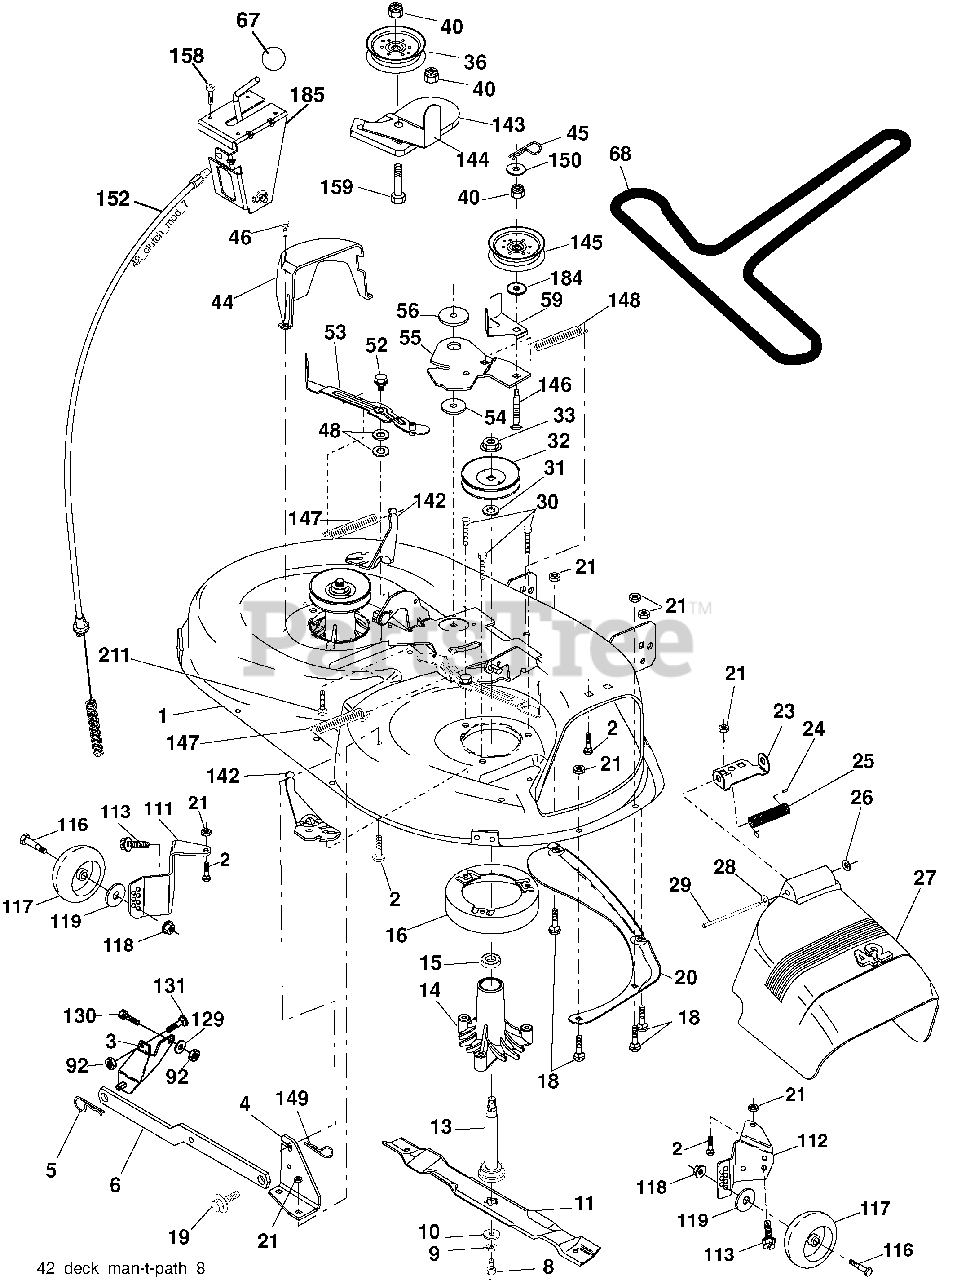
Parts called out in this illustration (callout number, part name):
1	Mower Deck Assembly, 42"
2	Bolt
3	Bracket Asm Fr. Sway Bar 3/42
4	Bracket Asm Deck 42" Sway Bar
5	Retainer Spring
6	Bar Sway Deck
8	Bolt 7/16-20
9	Washer, Lock
10	Washer, Hardened (The following Blades are available)
11	Blade Mower 42” Hi-Lift (for bagging and discharging)
11	Blade, Mulching 42” Std (for mulching mowers only)
11	Blade Mulching 42” Premium (For better wear when mulching)
13	Shaft As sem bly, Mandrel, Vented
14	Housing, Mandrel
15	Bearing, Ball, Mandrel
16	Stripper, Mandrel Deck
18	Bolt, Carriage 5/16-18 x 5/8
19	Bolt, Shoulder
20	Baffle, Vortex
21	Nut
23	Bracket, Deflector Mower 42"
24	Cap, Sleeve 80 x 112 Blk Mower
25	Spring, Torsion, Deflector 2 52
26	Nut, Push Phos & Oil
27	Shield, Deflector 42" Blk
28	Washer 11/32 x 5/8 x 16 Ga.
29	Rod, Hinge 42" 6 75 W/G
30	Screw Thdrol
31	Washer, Spacer Mower Vented
32	Pulley, Mandrel
33	Nut, Toplock
36	Pulley, Idler, Flat
40	Nut Lock 3/8-16
44	Guard, Mandrel, LH
45	Retainer
46	Screw, Thdrol 1/4-20 x 5/8 T
48	Washer, Hardened
52	Bolt, Shoulder 5/16-18 unc
53	Arm Assembly, Pad, Brake
54	Washer, Hardened
55	Arm, Idler
56	Spacer, Retainer
59	Guard TUV Idler
67	Knob Round
68	V-Belt, 42" Mower
92	Nut Lock Hex
111	Bracket Wheel Gauge LH
112	Bracket Wheel Gauge RH
113	Blt 5/16-18 Hex
116	Bolt SHLD
117	Wheel Gauge
118	Nut Centerlock 3/8-16
119	Washer 3/8 x 7/8 x 14 Ga.
129	Washer 13/32 x 13/16 x 12 Ga.
130	Bolt Fin Hex
131	Bolt RDHD SQNK
142	Arm Spring Brake Mower
143	Bracket Arm Idler 42"
144	Keeper Belt 42" Clutch Cable
145	Pulley Idler Flat
146	Bolt Carriage Idler
147	Spring Extension
148	Spring Return Idler
149	Retainer Spring Yellow
150	Washer 9/32 x 3/4 x 10 Ga.
152	Clutch Cable 42"
158	Screw Hex Thd Cut 1/4-20 x 1/2
159	Bolt Rdhd Sqn 3/8-16 unc x 1-3/4
184	Washer 13/32 x 7/8 x 10 Ga.
185	Head Asm Cable Clutch
211	Bolt Carr SH 3/8-16 x 1-1/2 Gr.5
211	Mandrel Assembly
211	Replacement Mower, Complete
